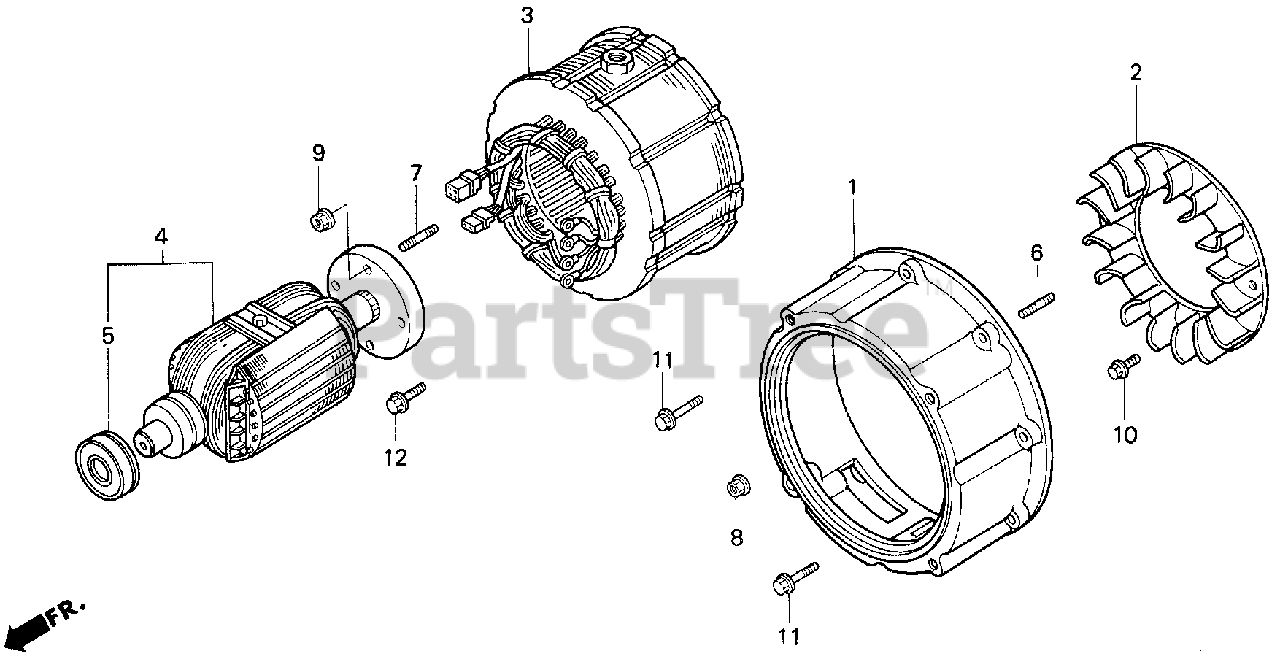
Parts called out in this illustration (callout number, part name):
1	HOUSING, FR.
2	FAN, GENERATOR COOLING
3	STATOR ASSY. (L)
5	BEARING ASSY. (6306NCX)
6	BOLT 2, STUD (8X32)
7	BOLT, STUD (10X40)
8	NUT, FLANGE (8MM)
9	NUT, FLANGE (10MM)
10	BOLT, FLANGE (8X20)
11	BOLT, FLANGE (8X35)
12	BOLT, FLANGE (10X35)
